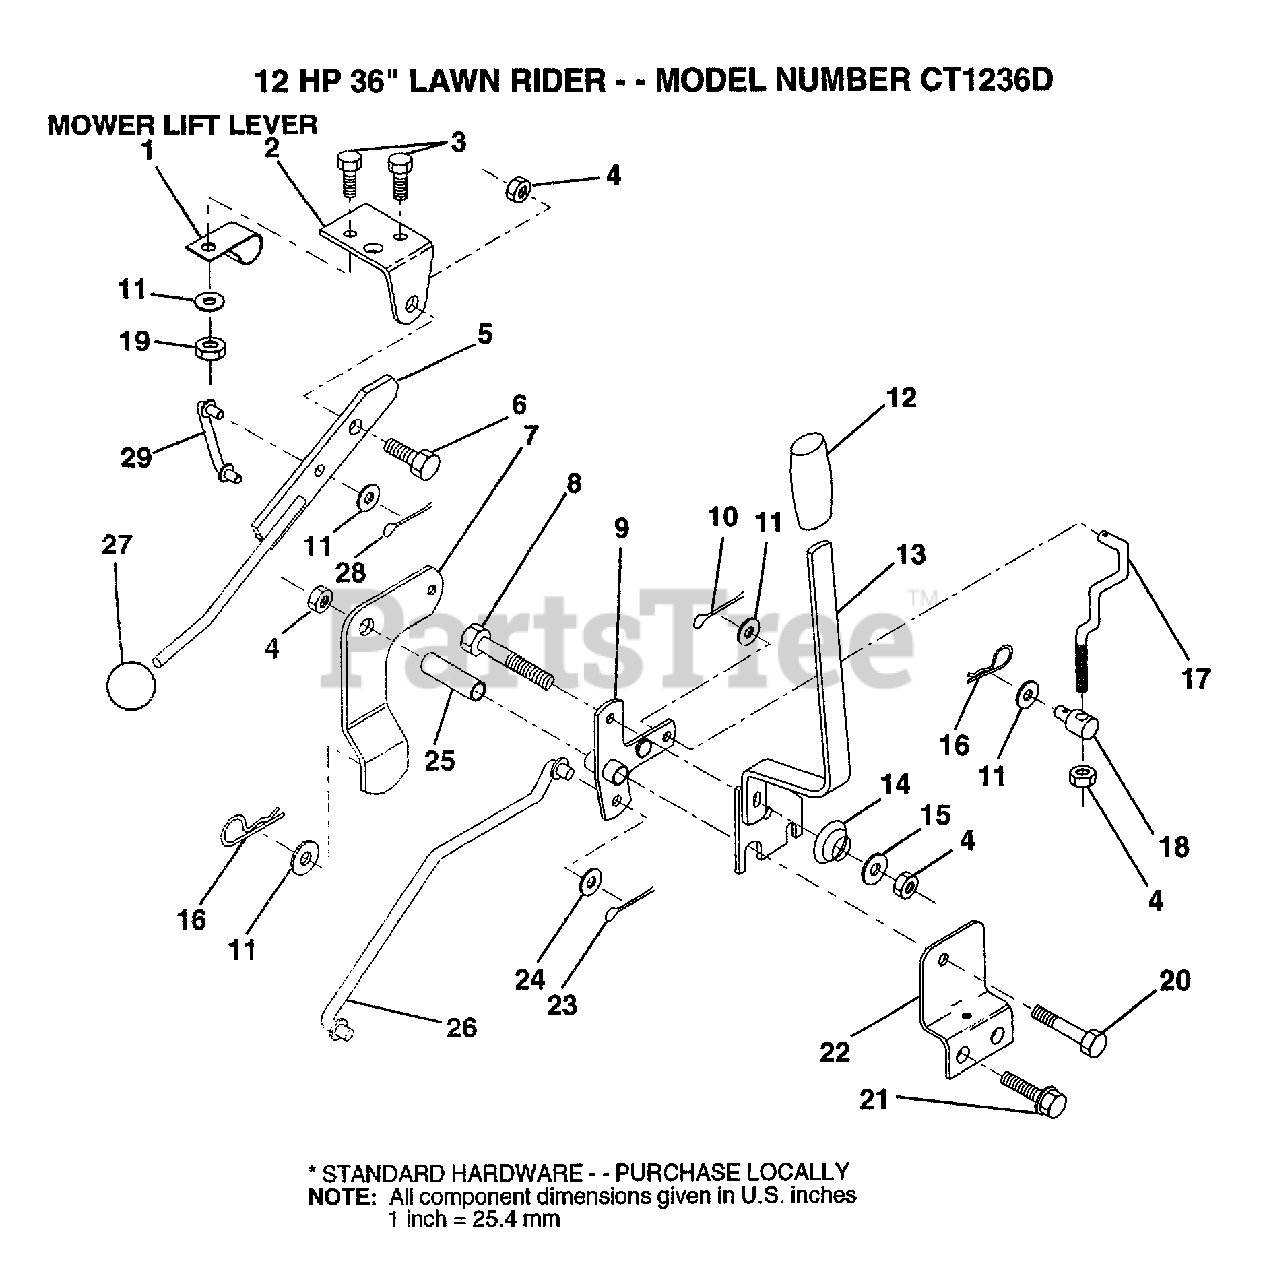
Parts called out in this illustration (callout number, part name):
1	"CLIP,INSULATOR"
2	BRKT CLUTCH
3	BOLT
5	CLUTCH LEVER AS
6	"BOLT, SHOULDER LT"
7	CLUTCH ARM ASS'Y
8	BOLT
9	"BELLCRANK,LIFT"
10	COTTER PIN
11	WASHER
12	GRIP HANDLE
13	"HDLE,LIFT T"
14	SPRING COMPRESSIO
15	WASHER T
16	SPRING.RETAINER
17	"LINK,LIFT FRT"
18	TRUNION
20	BOLT
21	SCREW LT
22	"BRKT,MOWER HGT"
23	PIN COTTER 1/8
25	TUBE SPACER
26	"ROD,MOWER LIFT "
27	KNOB
29	"LINK,MOWER LIFT"
